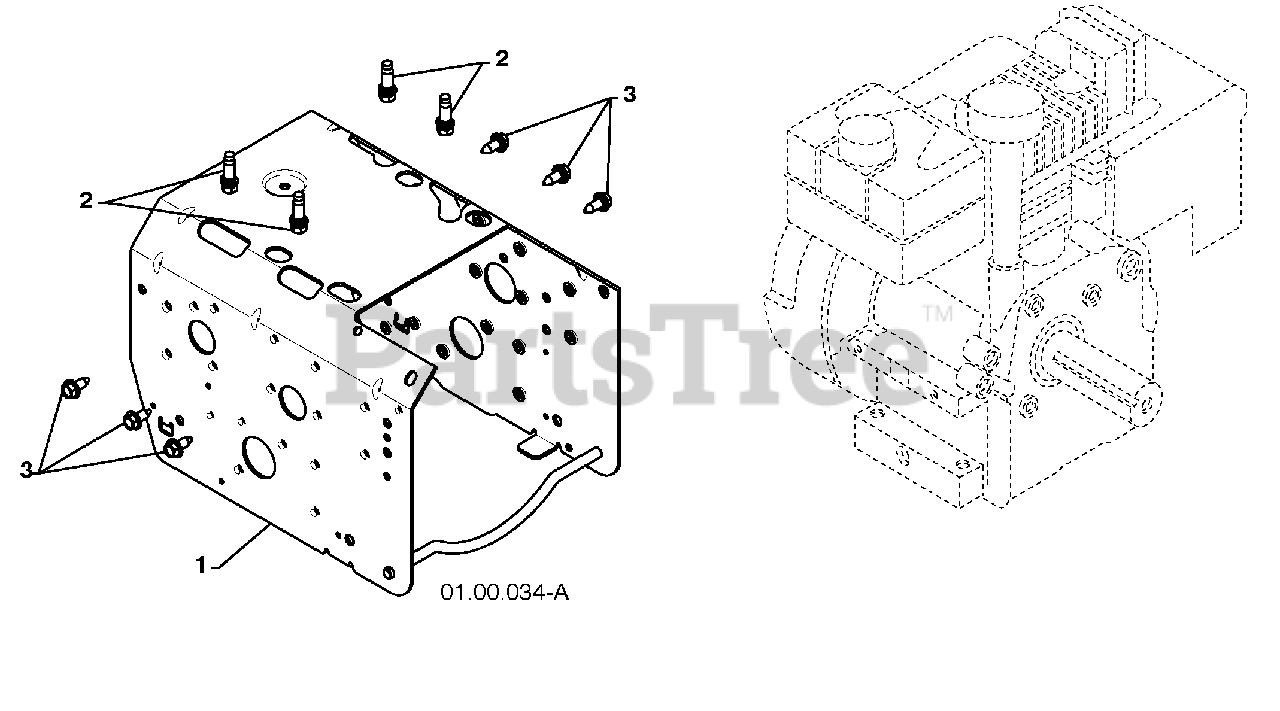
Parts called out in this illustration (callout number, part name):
1	FRAME
2	BOLT 3/8-16
3	SCREW 5/16-18 X .750
